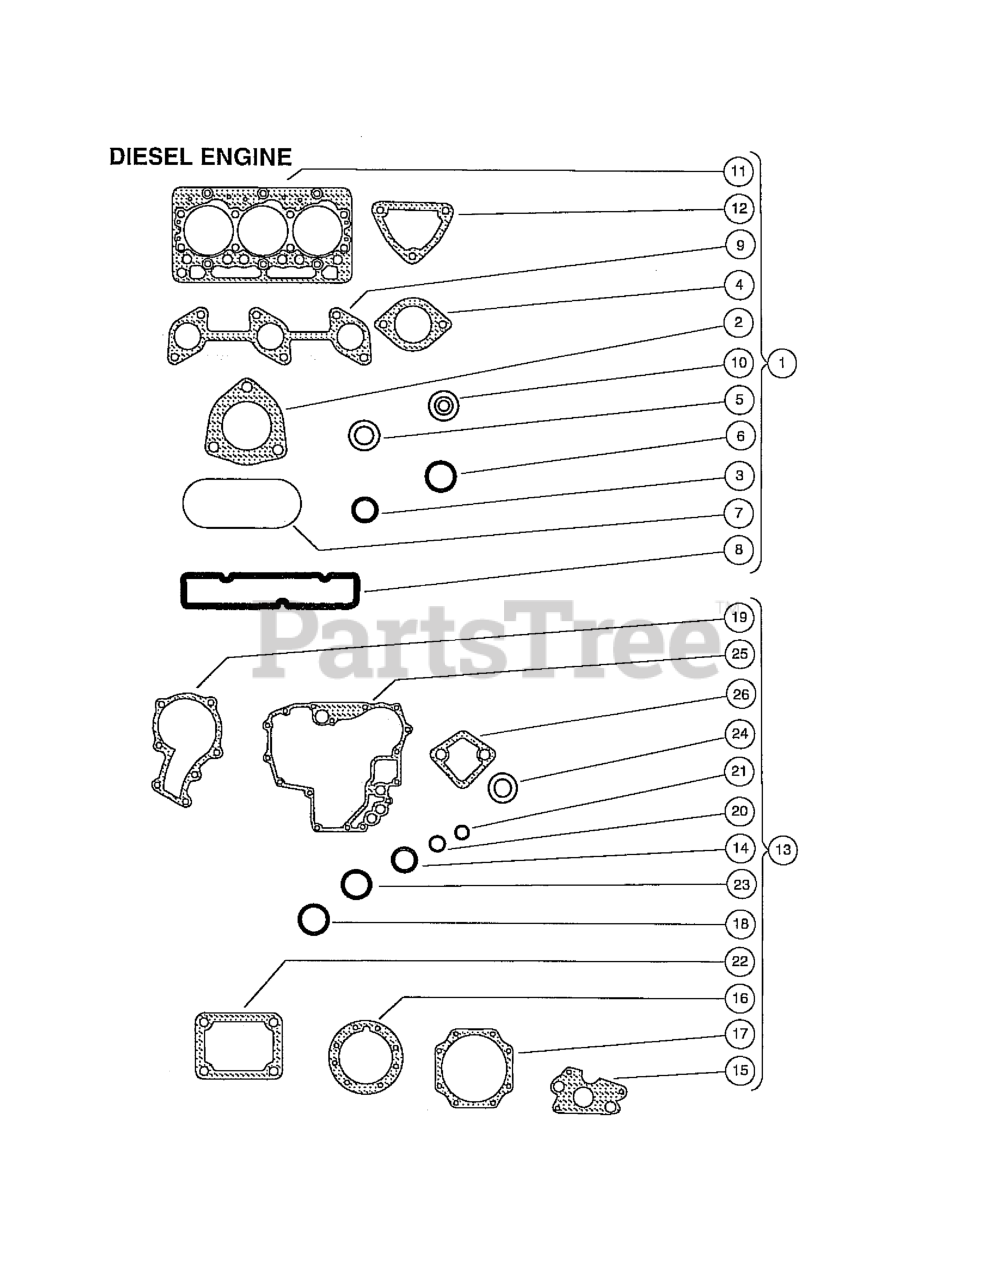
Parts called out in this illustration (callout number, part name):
1	KIT, GASKET UPPER, D722
2	GASKET, EXHAUST DIESEL
3	O-RING, 8 X 7
4	GASKET, THERMOSTAT
5	GASKET, 6X10
6	O RING, 30X36
7	GASKET, HEAD COVER
8	GASKET, IN-MANIFOLD
9	GASKET, EX-MANIFOLD
10	SEAL, VALVE STEM
11	GASKET, CYLINDER HEAD
12	GASKET, WATER FLANGE
13	KIT, GASKET LOWER, D722
14	O-RING, 18 X 13
15	GASKET, OIL PUMP NA
16	GASKET, BEARING CASE
17	GASKET, COVER
18	O RING, 23X26
19	GASKET, WATER PUMP, D722
20	O RING, 19X16
21	O RING, 9X7
22	GASKET, CONTROL PLATE
23	O RING, 20 X 17
24	GASKET, IDLE APPARATUS, REAR
25	GASKET, GEARCASE, D722
26	GASKET, FUEL PUMP, D722
